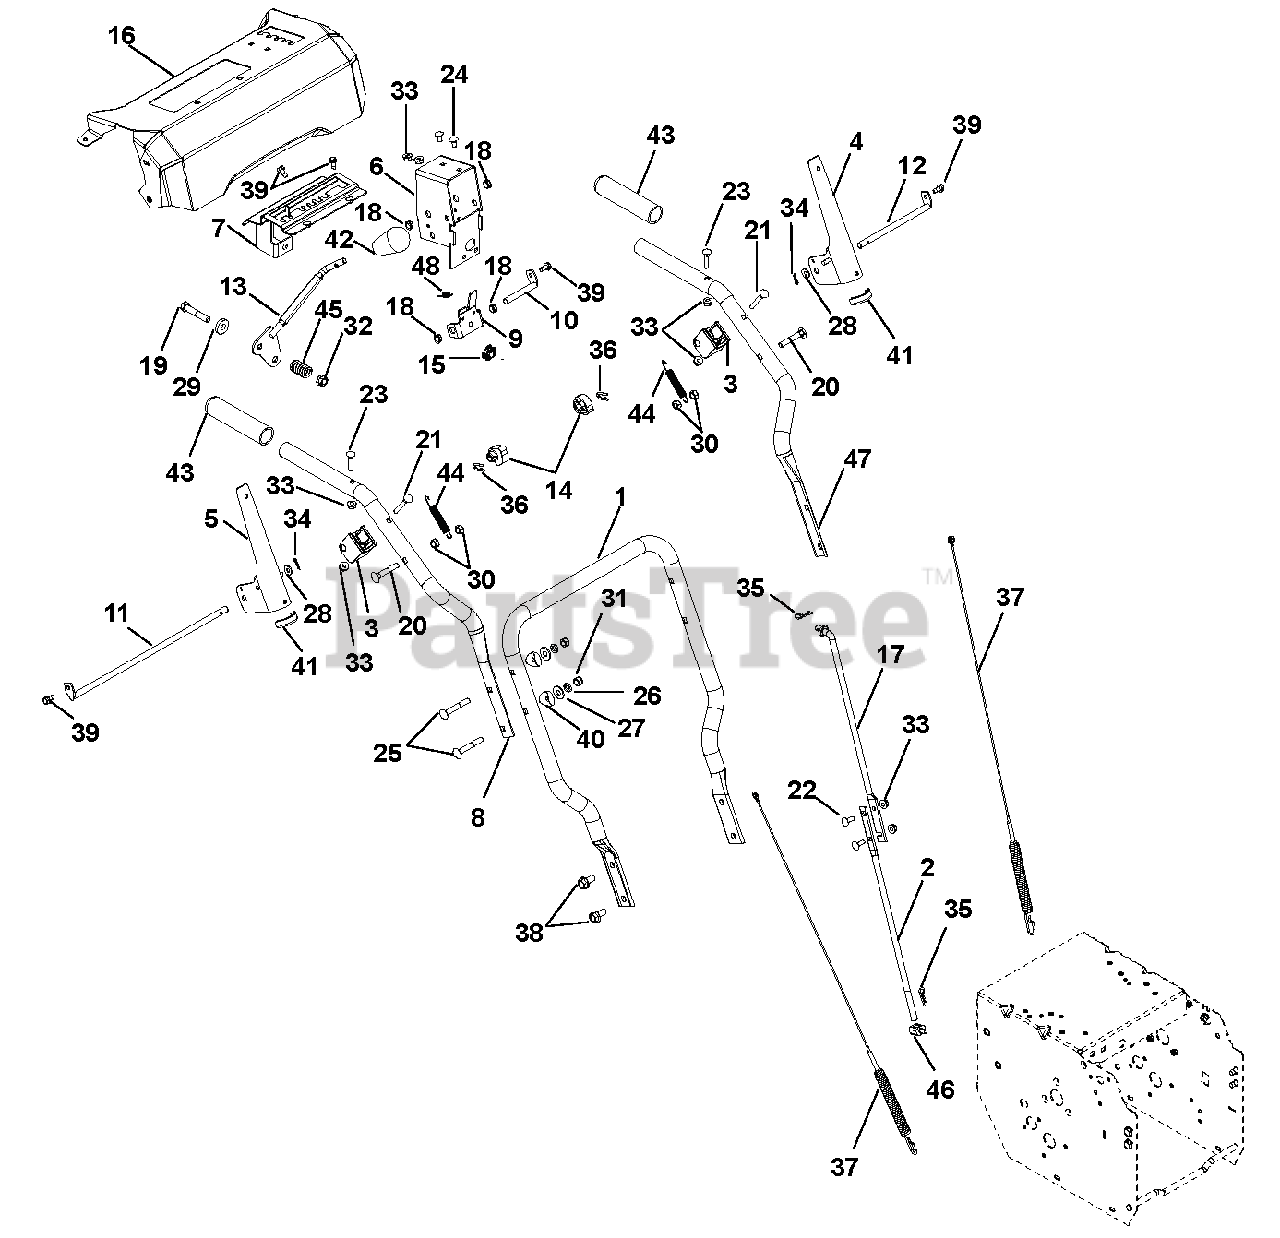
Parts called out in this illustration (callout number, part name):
1	HANDLEBAR, LOWER (COMPACT)
2	ROD, SHIFT - LOWER
3	BLOCK, CLUTCH PADDLE
4	LEVER, CLUTCH-LH
5	LEVER, CLUTCH-RH
6	WELDMENT, BRACKET INTERLOCK
7	WELDMENT, DETENT PLATE-COMPACT
8	HANDLEBAR, UPPER - RH
9	BRACKET, INTERLOCK ARM
10	ROD, PIVOT - INTERLOCK
11	ROD, PADDLE MOUNT - LONG
12	ROD, PADDLE MOUNT - SHORT
13	LEVER, CONTROL-SHIFT(WELDMENT)
14	CAM, INTERLOCK
15	CRANK BUSHING, NYLON CHUTE BK
16	CONTROL PANEL W/DECAL, SNO-TEK
17	ROD, SHIFT - UPPER
18	BUSHING, POLYLINER-.38 SNAPIN
19	@BLT-HEX .38-16X2.00 GR5 YWZC
20	BLT-RDHDXLSQNK .31-18X2.0 G5YZ
21	BLT-RDHDXLSQNK .25-20X2.0 G5YZ
22	@BLT-RDHDSQNK .25-20X.75 G5YZ
23	BLT-RDHDXLSQNK.25-20X1.25 G5ZC
24	@BLT-RDHDSQNK .25-20X.50 G5YZ
25	@BLT-RDHDSQNK .31-18X2.25 G5YZ
26	WSHR-LK .312X.097 HVY YWZC
27	@WSHR-FL-STL.38X.875X.083 YWZC
28	@WSHR-FL-STL.281X.62X.065 YWZC
29	WSHR-FL-STL .406X1.00X.188 YWZ
30	@NUT-LK-CTR .31-18 YWZC
31	@NUT-LK-NYL .312-18 YWZC
32	@NUT-LK-TOP-FLG .38-16 YWZC
33	@NUT-LK-TOP-FLG .25-20 YWZC
34	PIN-HAIR INT .06X.18X.77
35	PIN-HAIR INT .08X.18X1.18 YWZC
36	PIN, SPRING CLIP
37	CABLE, AUGER & UPPER TRACTION
38	BLT-SERHFWH .38-16X.75 YWZC
39	SCR-TAP .25-20X.50 HWH TR YWZ
40	SPACER, HANDLEBAR
41	EDGING, CLUTCH PADDLE - 2.00"
42	KNOB,SOFT TEARDROP,PUSH-ON BLK
43	HANDLE GRIP
44	SPRING, EXTENSION
45	SG-COMP .125X.781X1.250
46	PIVOT,SHIFT ROD .375-16(TRUNN)
47	HANDLEBAR, UPPER - LH
48	SPRING-EXT .047X.438X1.45
